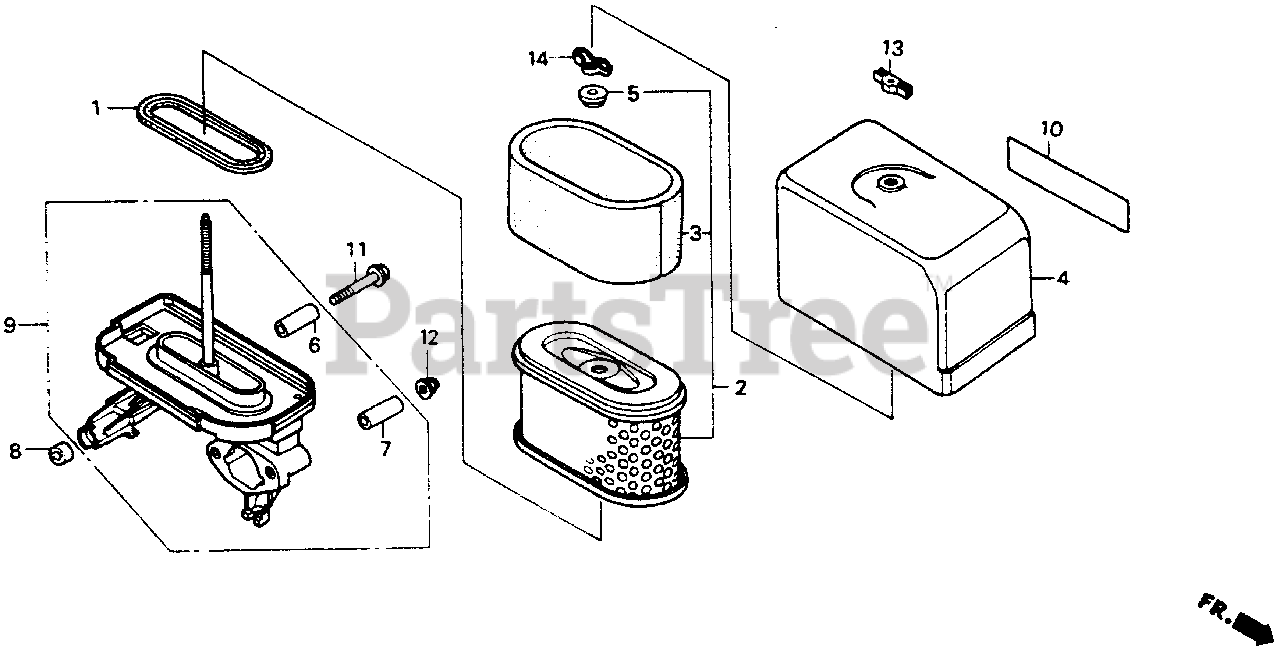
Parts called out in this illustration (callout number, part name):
1	GASKET, ELBOW
2	ELEMENT, AIR CLEANER
2	ELEMENT, AIR CLEANER (METAL BASE)
3	FILTER (OUTER)
4	COVER, AIR CLEANER (DUAL)
5	GROMMET, AIR CLEANER
6	COLLAR, AIR CLEANER
7	COLLAR, AIR CLEANER
8	SPACER, AIR CLEANER ELBOW
9	ELBOW SET, AIR CLEANER
9	ELBOW, AIR CLEANER
10	MARK, AIR CLEANER CAUTION
11	BOLT, FLANGE (6X40)
11	BOLT, FLANGE (6X45) (CT200)
12	NUT, CAP (6MM)
13	WINGNUT (6MM) (BLACK)
13	WINGNUT
14	NUT, TOOL BOX SETTING
